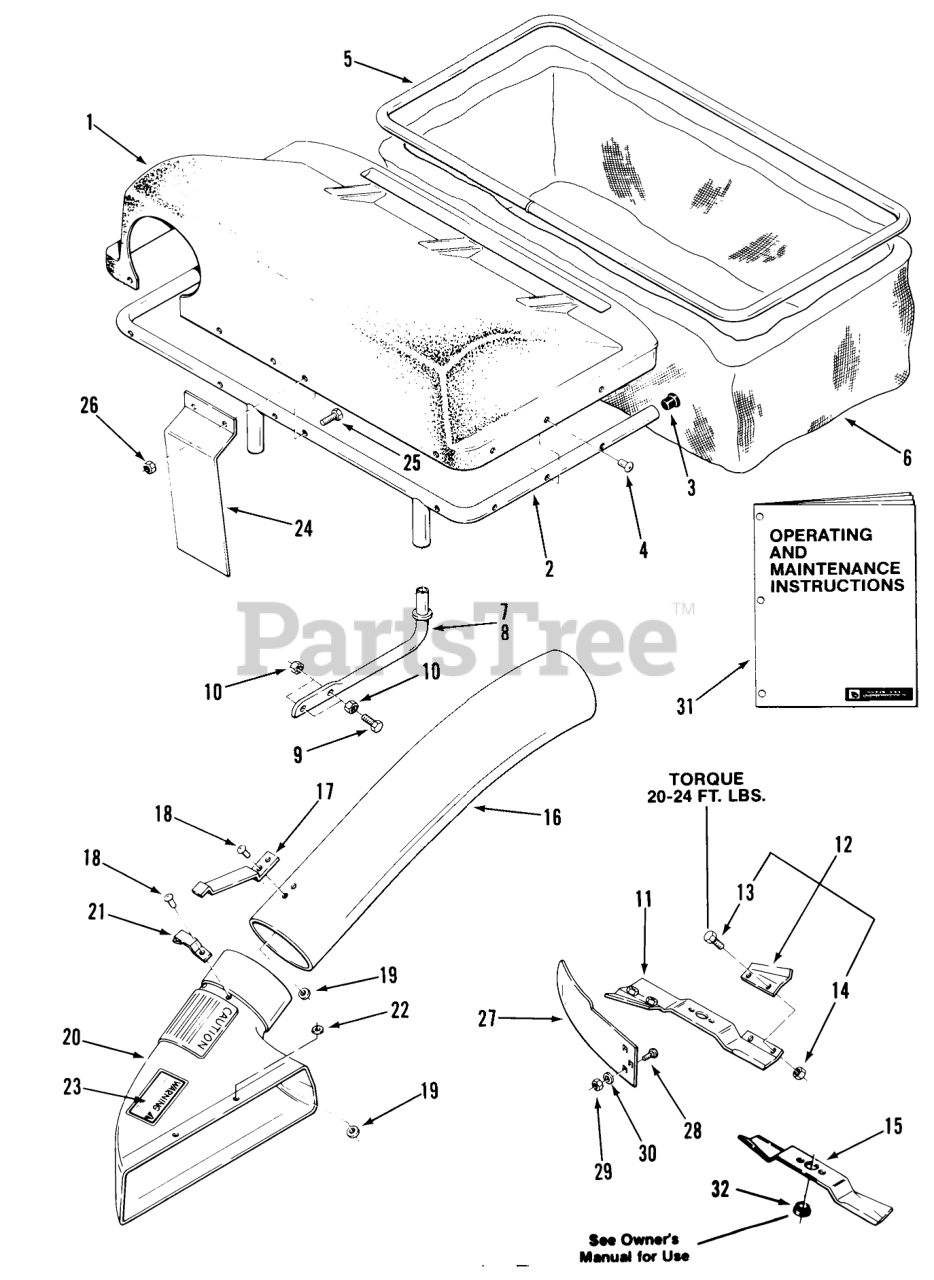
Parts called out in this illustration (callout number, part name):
2	Frame
4	RIVET
5	FRAME-BAG B
6	Bag
7	Support Rod LH
8	ROD-QUICK ATTACH RH
9	Bolt
10	Nut
11	High Lift Blade
12	Lift Tab Kit (Includes 13, 14)
13	BOLT 5/16-18X5/8
14	NUT-LOCK 5/16-18
15	BLADE 16.50
16	CHUTE
17	SPRING-TUBE
18	POPRIVET
19	WASHER
20	Elbow
21	BRACKET
22	Collar
23	DECAL-WARNING
24	SHIELD MUFFLER
25	Bolt 1/4-20 X 1 1/2
26	Nut
27	BAFFLE-DEFLECTOR B
28	Bolt Carnage
29	Nut
30	Lockwasher
31	Operating and Maintenance Instructions
31	Operation and Maintenance Instructions
32	SPACER BLADE
